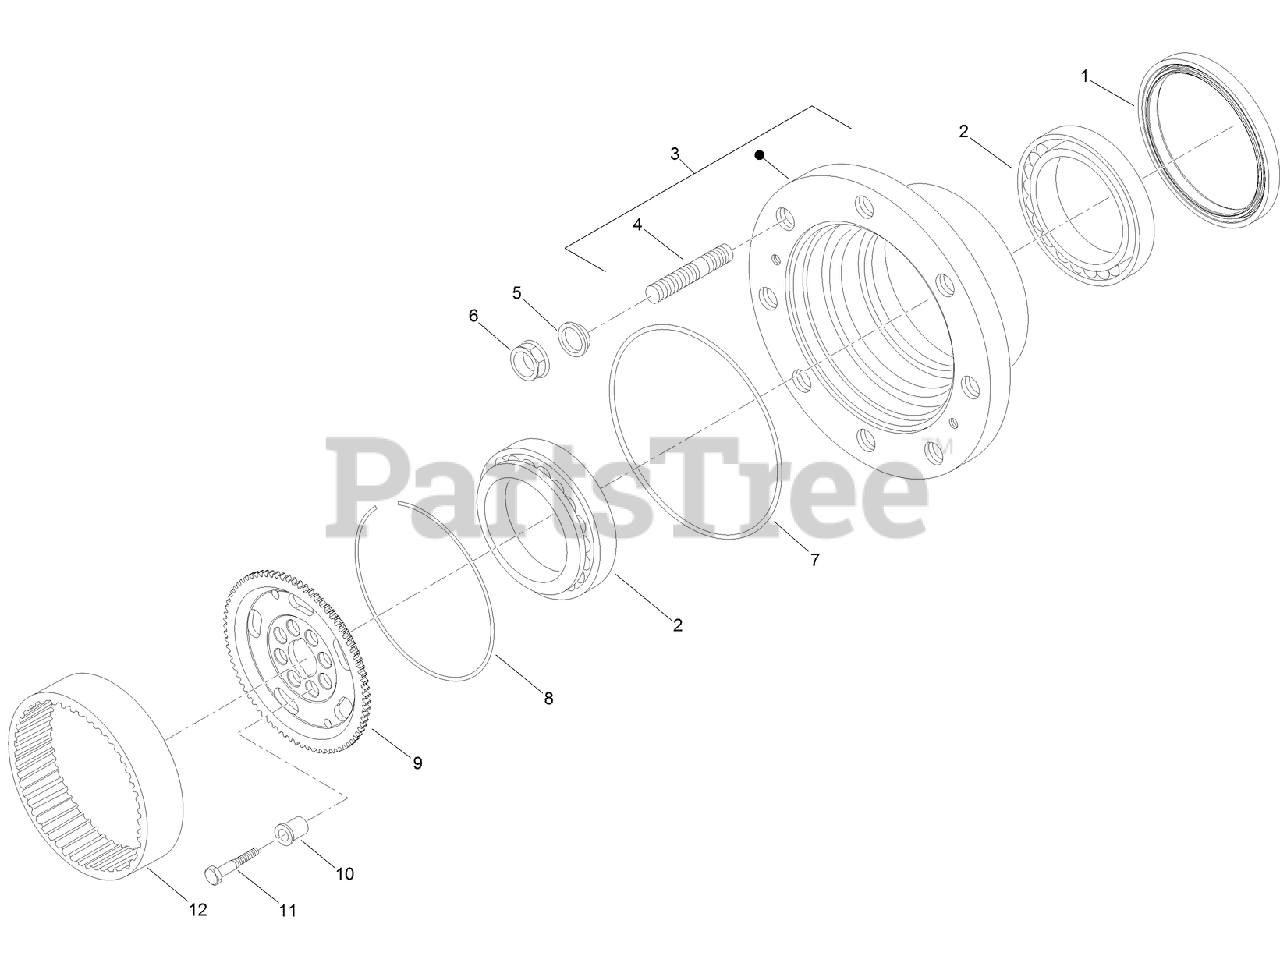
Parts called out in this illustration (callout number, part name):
1	RING-SEAL
2	BEARING
3	WHEEL HUB KIT
4	STUD-WHEEL
5	WASHER-LOCK
6	NUT-LUG
7	O-RING
9	CARRIER-WHEEL
10	BUSHING-CENTERING
12	GEAR-CROWN
